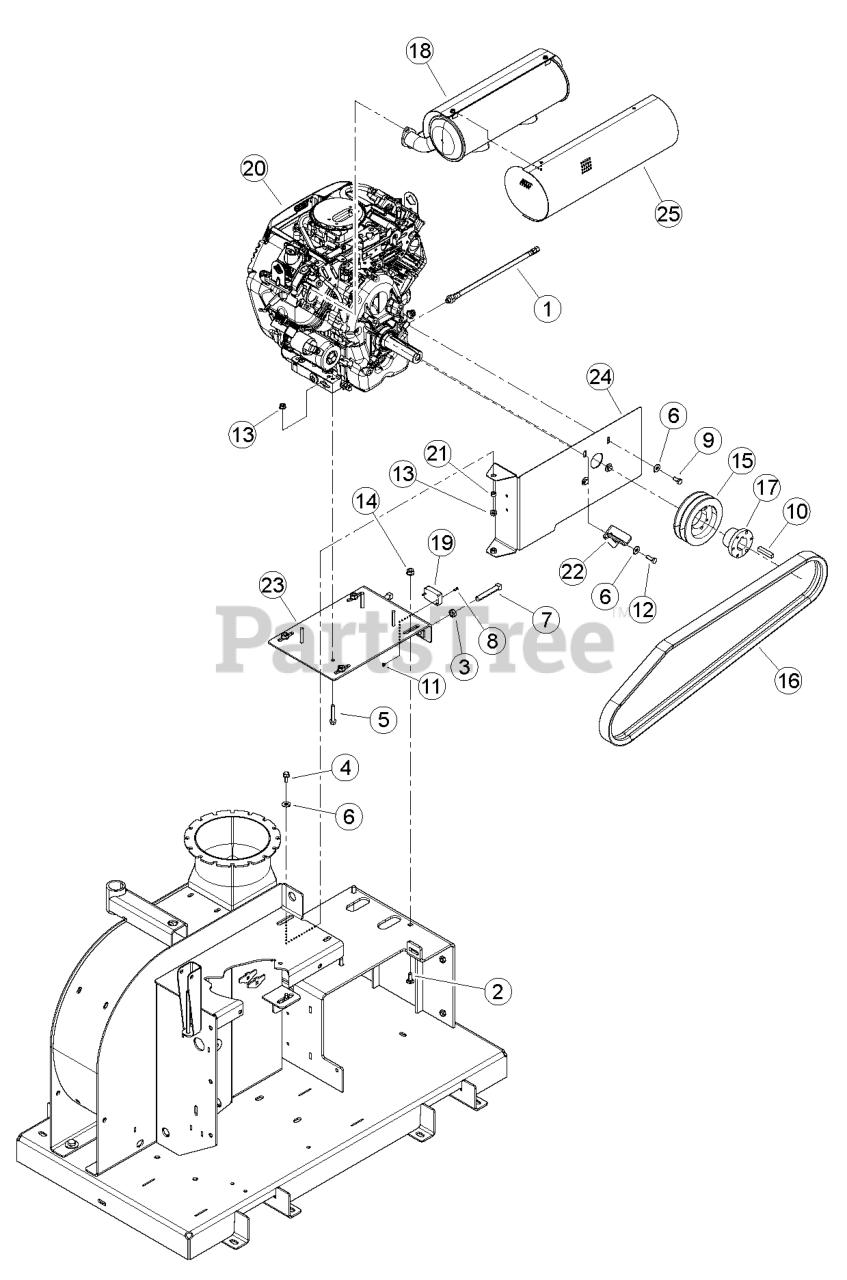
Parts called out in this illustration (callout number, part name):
1	HOSE ASSEMBLY, CRANKCASE DRAIN
2	BOLT, 3/8-16 X 1 GR5 CRG
3	NUT, 1/2 NC ZP JAM
4	BOLT, 5/16 X 3/4 FLANGE NC
5	BOLT, 5/16 X 2 FLANGE NC
6	WASHER, 5/16 FLAT
7	SETSCREW, 1/2 X 3 SQ HD 1/2 DOG PT
8	SCREW, #6-32 X 3/4 PAN PHP ZP
9	BOLT, 5/16-24 X 3/4" GR5 HHCS ZP
10	KEY, 3/8" SQ X 2" LG PLAIN
11	NUT, #6-32 NYLON LOCK ZP
12	BOLT, 5/16-24 X 1" HHCS GR5 ZP
13	NUT, 5/16-18 NYLOCK FLANGE
14	NUT, 3/8-16 NYLOCK FLANGE
15	SHEAVE, 2B5.2 SDS
16	BELT, 2B70 BANDED ARAMID
17	BUSHING, SD 1-7/16"
18	MUFFLER, BRIGGS 25 HP (FOR SERVICE SEE ENGINE OWNER'S MANUAL OR NEAREST BRIGGS & STRATTON INDUSTRIAL ENGINE DEALER)
19	METER, TACH/HOUR
20	ENGINE, 25 HP BRIGGS (FOR SERVICE SEE ENGINE OWNER'S MANUAL OR NEAREST BRIGGS & STRATTON INDUSTRIAL ENGINE DEALER)
21	SPACER, .334 X .50 X .29
22	GUIDE, BELT DL ENGINE MOUNT
23	WELDMENT, ENGINE PLATE
24	PLATE, DL ENGINE SHIELD
25	WELDMENT, SHIELD HEAT
